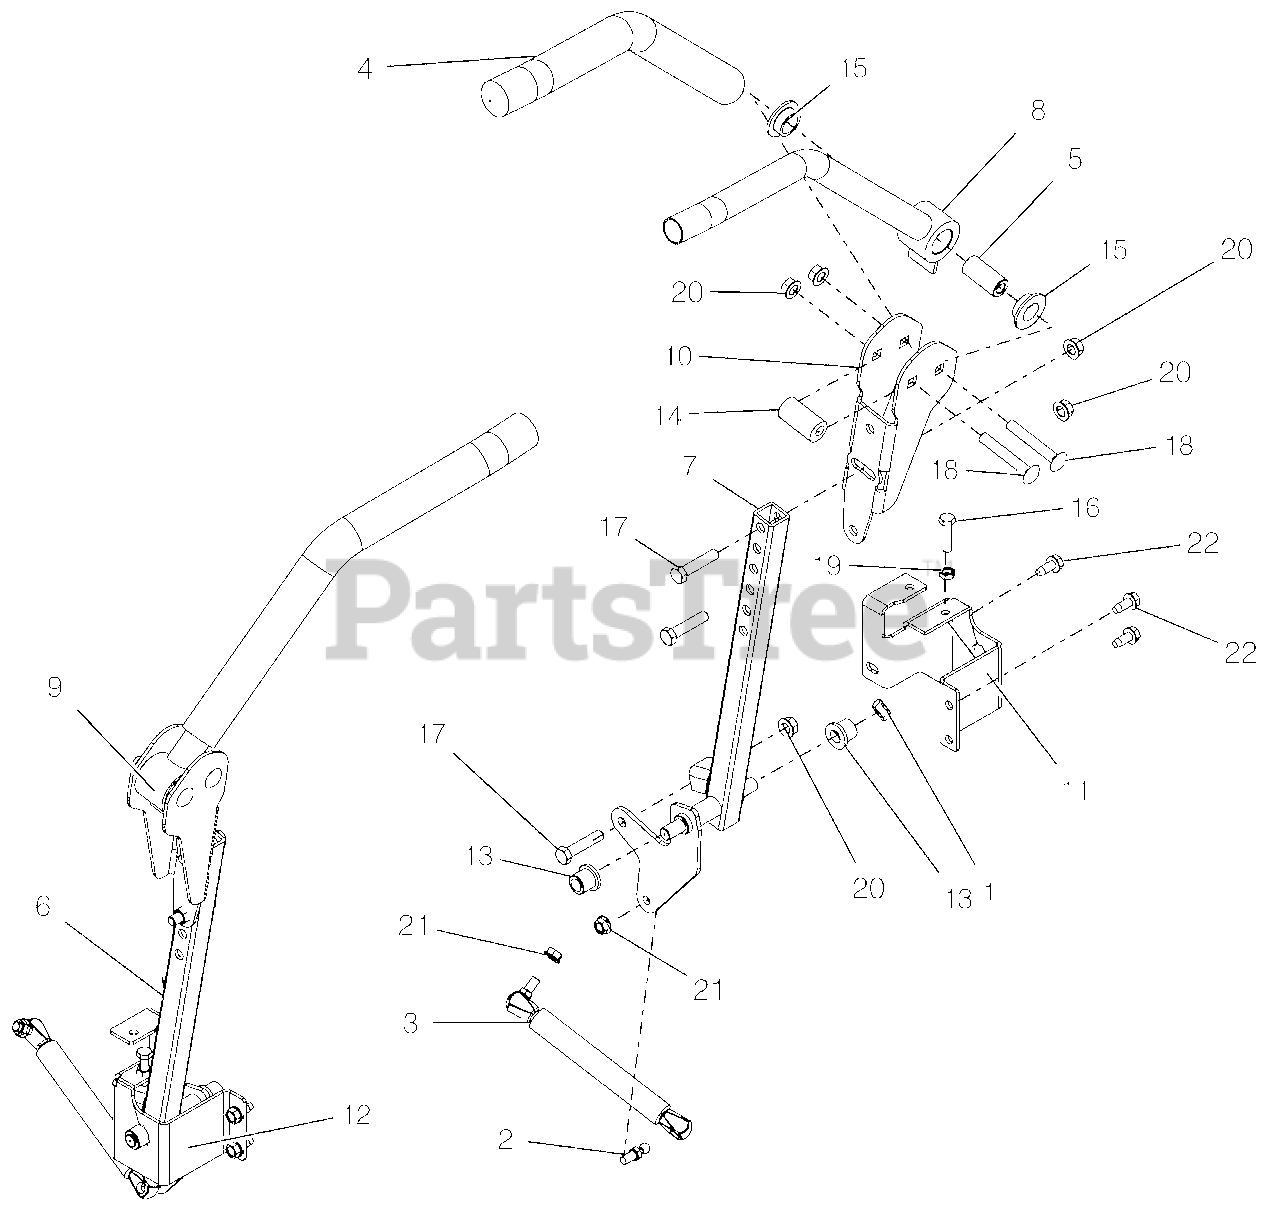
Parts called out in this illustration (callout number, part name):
1	WAVE WASHER .531X.781X.125FH
2	STUD- BALL
3	DAMPER
4	GRIP, HANDLEBAR
5	SPACER, STEERING ARM
6	WLDMT, STEERING RH
7	WLDMT, STEERING LH
8	WLDMT, CONTROL HANDLE- BLK
9	WLDMT, CONTROL HANDLE- BLK
10	ADJ UPPER CONTROL ARM BRKT-BLK
11	BRKT, STEERING ARM MOUNT -LH
12	BRKT, STEERING ARM MOUNT -RH
13	BHSG-FLG .500X.750X.750X.125
14	BSHG, ECCENTRIC.406X.875X1.625
15	BSHG-FLG .762X1.48X.44 NYL
16	@BLT-HEX .31-18X1.25 GR5 YWZC
17	@BLT-HEX .38-16X1.75 GR5 YWZC
18	BLT-RDHDSQSHK, 38-16X2.50 G5YZ
19	NUT- JAM .312-18 YWZC
20	@NUT-LK-TOP-FLG .38-16 YWZC
21	@NUT-LK-TOP-FLG .31-18 YWZC
22	@SCR-TAP .31-18X.75 HWH TR YWZ
